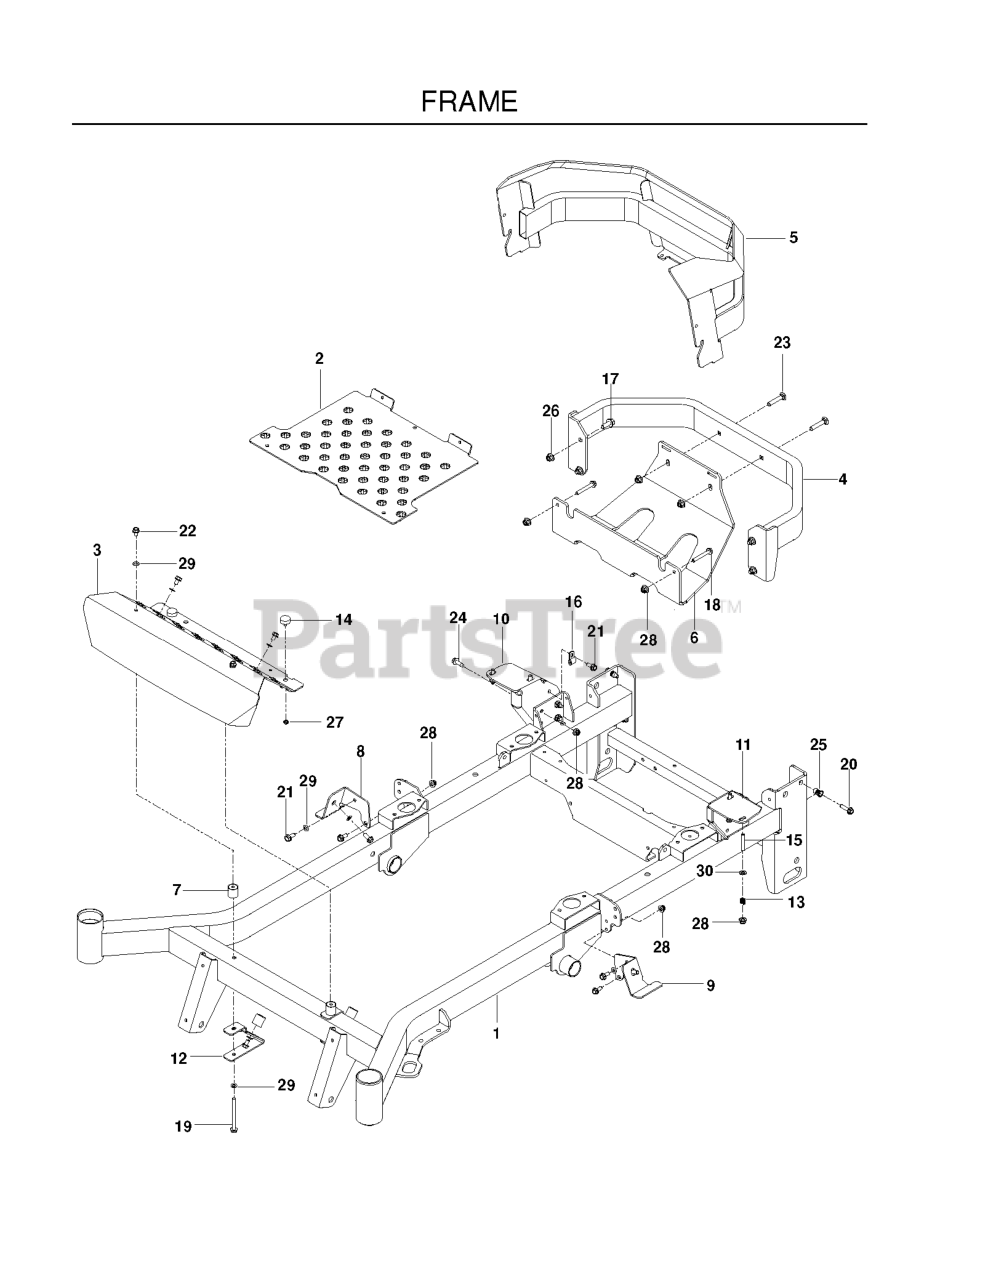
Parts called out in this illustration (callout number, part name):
1	FRAME W/DECALS, PZ
2	PLATE, FLOOR PAN, OR
3	PLATE, FOOT REST, OR
4	BUMPER.REAR.ORANGE
5	GUARD, REAR, GRAY
6	PLATE, SKID GRAY
7	MOUNT, F/F INSERT
8	MOUNT, RT TANK, BLK
9	MOUNT, LT TANK, BLK
10	XX MOUNT, TANK, RT-BLK
11	MOUNT, TANK, LT-BLK
12	BRACKET, REST MOUNT
14	BUMPER, 1/4-20 STUD, 1/4
15	STUD, 5/16C
16	DOUBLE TUBE CLAMP
17	HHFS 3/8-16 X 1 GRD 5 ZD
18	HHFS 5/16-18 X 2.25 GD 5
19	HHFS 5/16-18 X 3 3/4
20	HHFS 5/16-18 X 1.25 TPBLT GD 5
21	HHFS 5/16-18 X 3/4
22	SCR 5/16-18 X 1/2 SELFTAP ZN
23	RHSNB 3/8C X 2
24	RP BLT 5/16-18 X 1 THRD FORM D
25	NUTSERT 5/16-18 THICK GRIP
26	NUT 3/8-16 HEX FLG NYLOC ZD
27	JAM NUT 1/4C (2 2 PW01)
28	5/16-18 NYLOC FLANGE NUT
29	WASH 5/16 DISC SPRING ZD
30	FLAT WASHER 5/16 SAE
